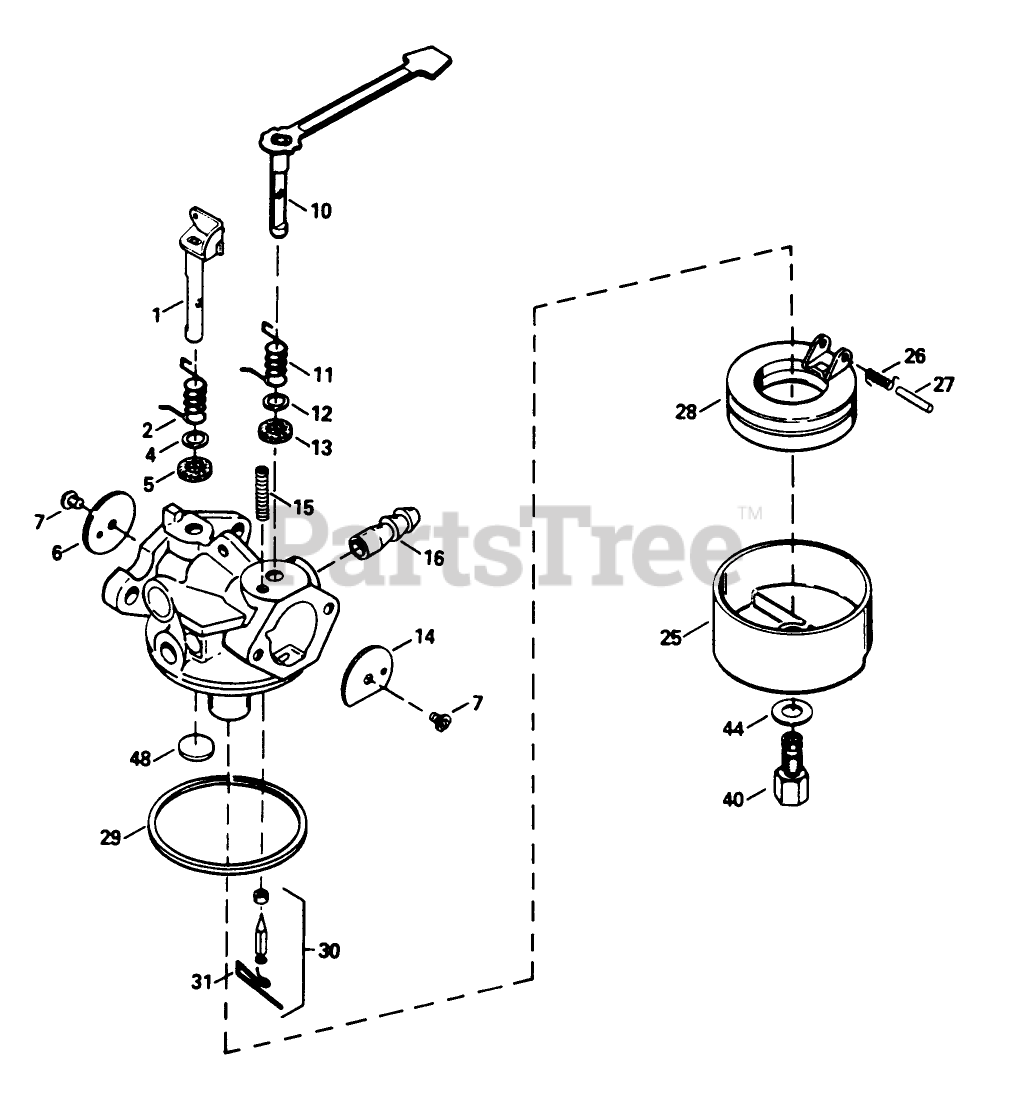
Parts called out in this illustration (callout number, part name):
1	Throttle Shaft Lever Asm.
2	Spring-Trottle, Return
4	Washer-Seal, Dust
5	Seal-Dust
6	Shutter-Throttle
7	Screw-Shutter
10	Choke Shaft and Lever ASM
14	Shutter-choke
15	Spring-Positioning, Choke
16	Fitting-Fuel
25	Bowl Float
26	Spring-Float, Dampening
27	Shaft-Float
28	Float
29	O Ring-Bowl, Float
30	Inlet Needle, Seat Clip Assy. (Incl. No. 13)
31	Clip-Spring
40	Nut-Float Bowl
44	Gasket-Bowl
48	Plug-Welch, Atmospheric Vent
